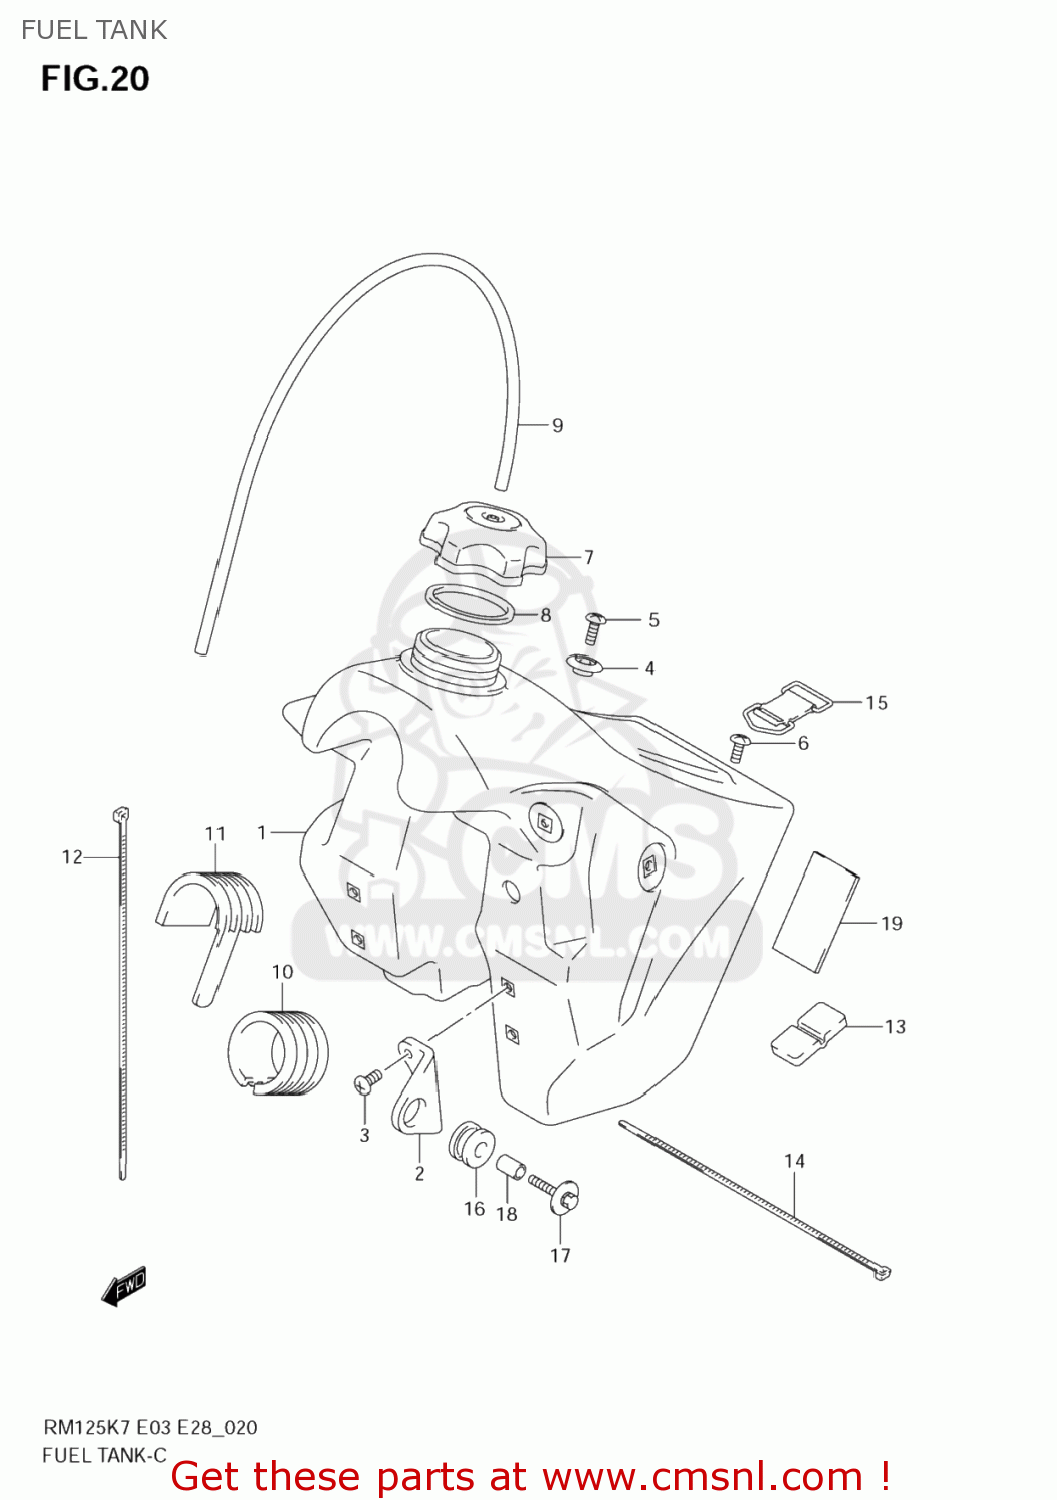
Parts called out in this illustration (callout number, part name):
1	TANK,FUEL(YELLOW)
2	BRACKET,FUEL TANK FR
3	SCREW
4	HOOK,SEAT FR
5	SCREW
6	SCREW(6X13.5)
7	CAP,FUEL TANK FILLER
8	GASKET,CAP (NAS)
9	HOSE(5X8.2X600)
10	CUSHION,FUEL TANK NO.1
11	CUSHION,FUEL TANK
12	CLAMP(L:300)
13	CUSHION,FUEL TANK RR
14	CLAMP(L:250)
15	BAND,FUEL TANK RR
16	CUSHION,MUFFLER
17	BOLT(6X35)
18	SPACER(6.5X9X13.5)
19	PROTECTOR(40X85X5)
